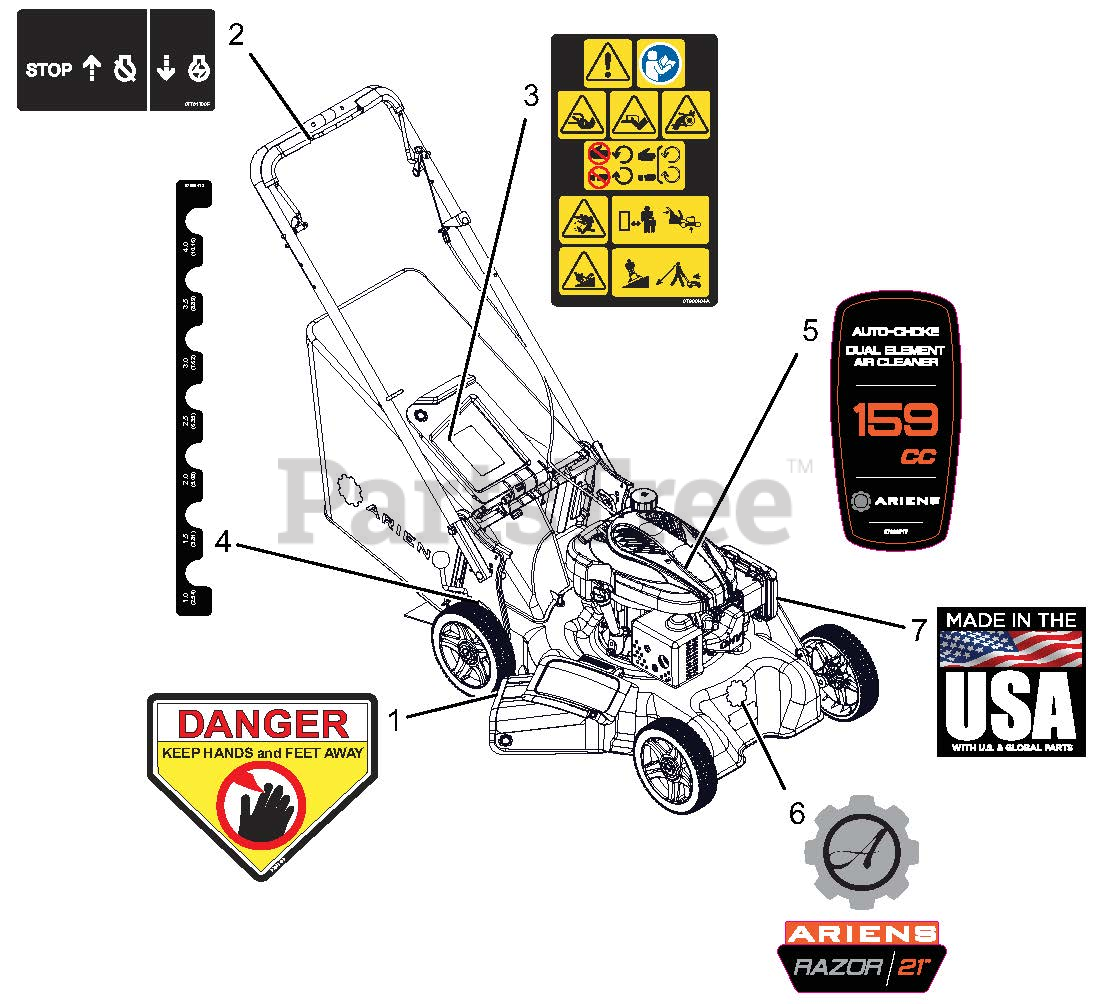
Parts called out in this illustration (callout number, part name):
1	DECAL, DANGER
2	DECAL - ENGINE CONTROL
3	DECAL,MAIN SAFETY_WAW LM
4	DECAL, HOC
5	DECAL-ENGINE STYLE-RAZOR
6	DECAL-ARIENS RAZOR 21"
7	DECAL, MADE IN USA
